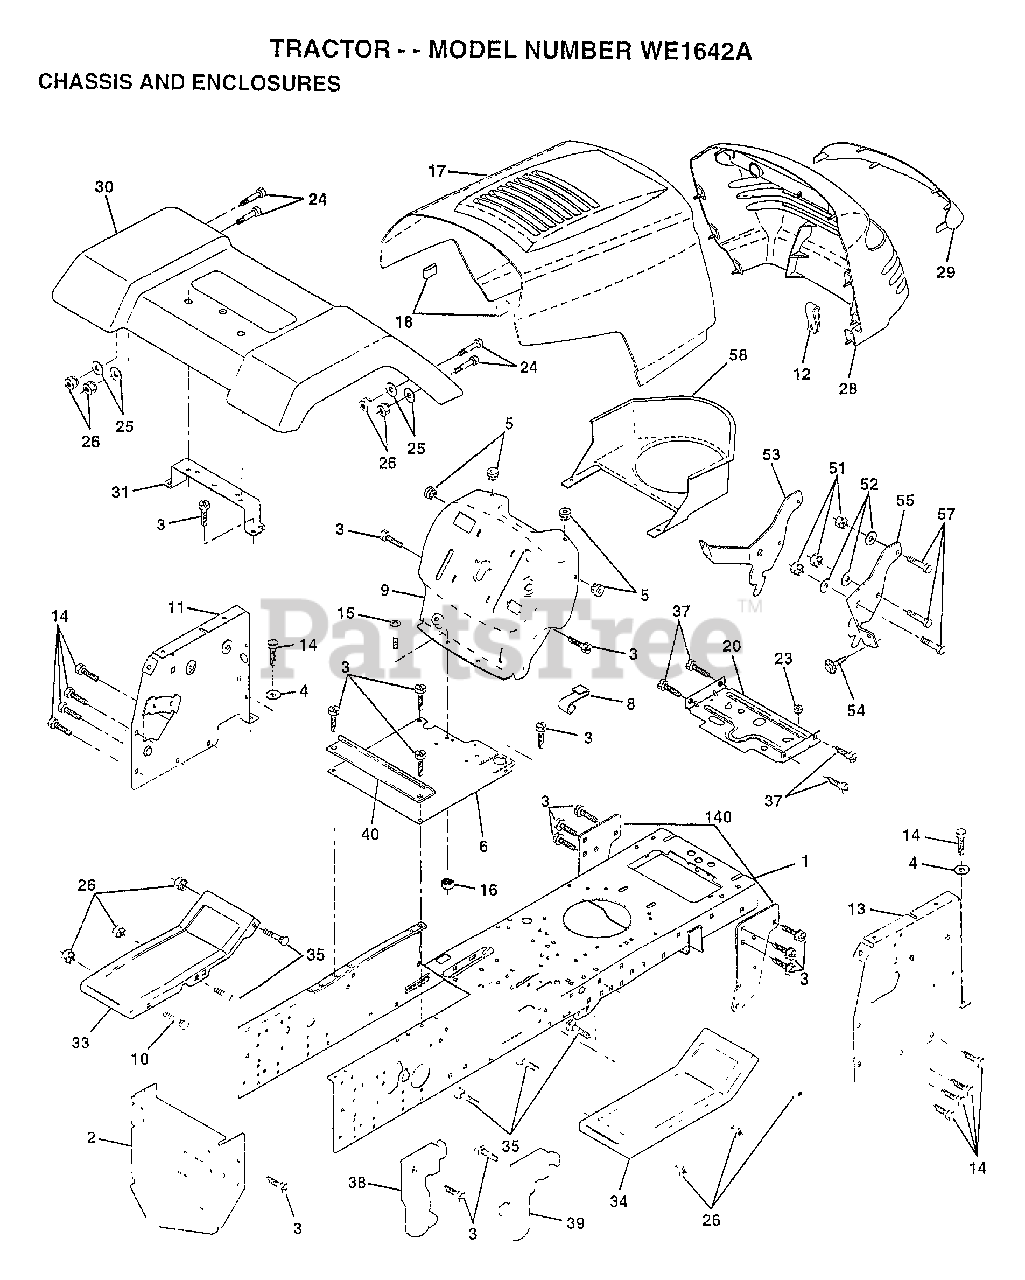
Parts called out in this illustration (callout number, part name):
1	CHASSIS ASM
3	SCREW
4	WASHER
5	BUMPER-HOOD/DASH
6	SADDLE
8	"CLIP,INSULATOR"
9	DASH.SILKSCREENED
11	"PANEL-DASH,LH"
12	CLIP.TINNERMAN
14	SCREW LT
15	SCREW
20	"PLATE-MTG,BATT/FU"
24	BOLT
25	WASHER
26	NUT
28	GRILLE-MS428
29	LENS GRILLE
30	FENDER
31	BRACKET SUPT FEND
33	FOOTREST.LH.LT/GT
34	FOOTREST.RH.LT/GT
35	BOLT
37	SCREW LT
38	BRACKET ASM LH
39	BRACKET ASM RH
40	SPACER FENDER LT
51	NUT
52	WASHER
53	BRACKET.GRILLE.LH
55	BRACKET.GRILLE.RH
58	DUCT.AIR.B&S.18HP
140	BRKT SUSPENSION
